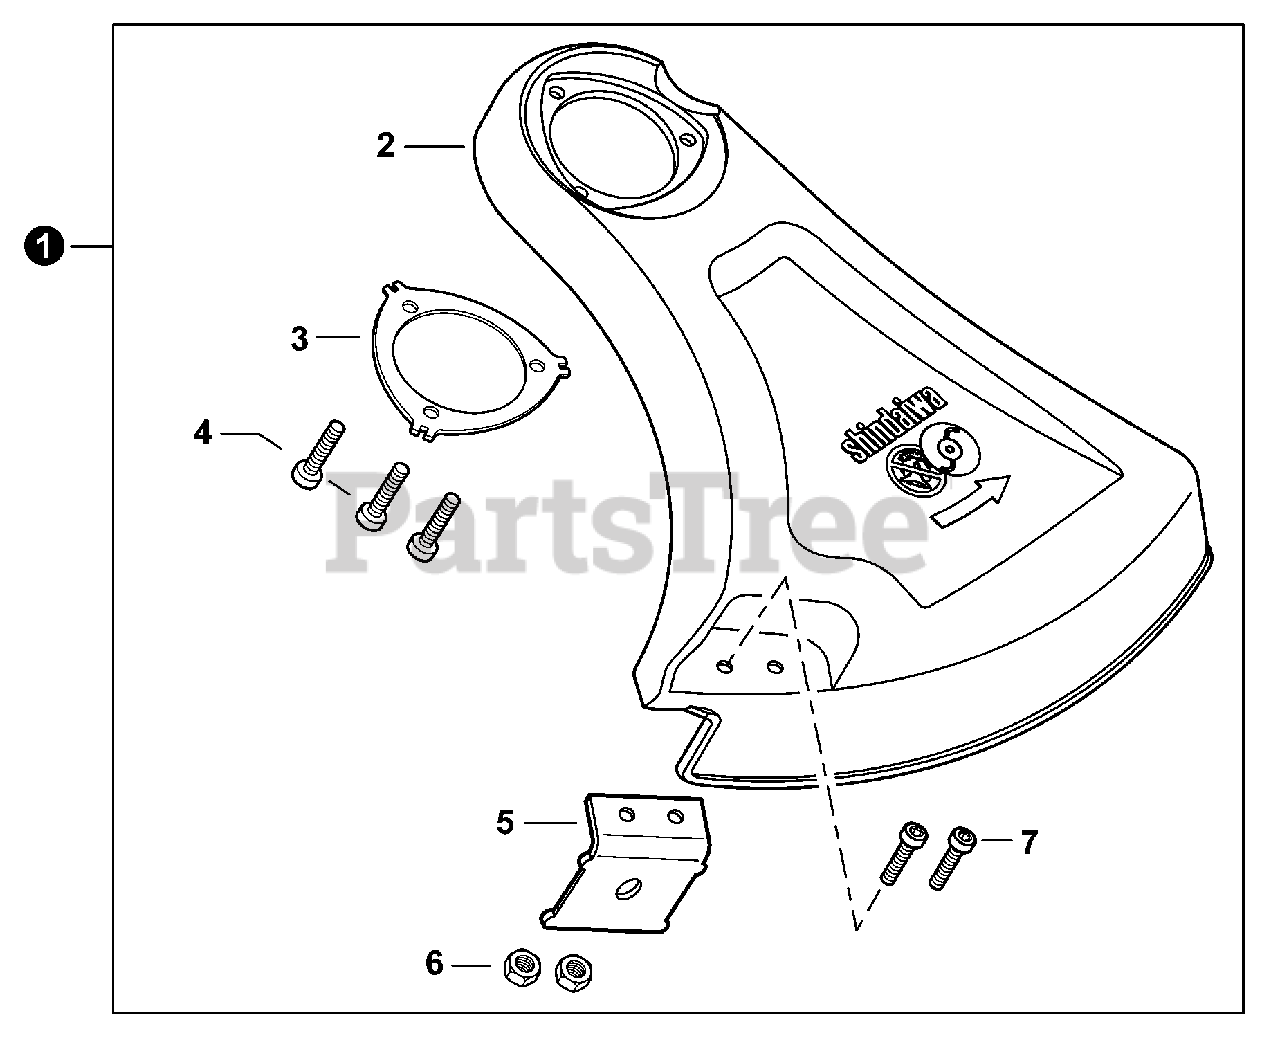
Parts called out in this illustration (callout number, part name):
1	DEBRIS SHIELD ASSY
2	SHIELD, DEBRIS
3	PLATE, SHIELD
4	BOLT, TORX 5×16
5	CUTTER, LINE
6	NUT M5
7	BOLT, TORX 5×12
